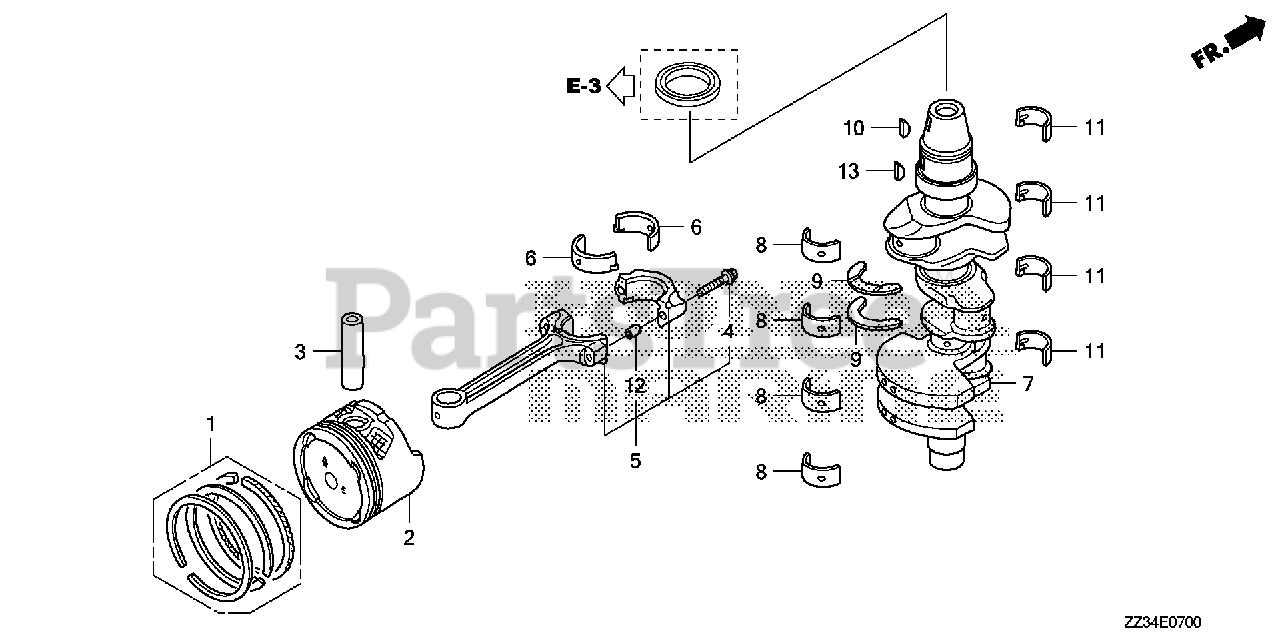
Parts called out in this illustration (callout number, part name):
1	RING SET, PISTON (STD) (RIKEN)
2	PISTON
3	PIN, PISTON
4	BOLT, CONNECTING ROD
5	ROD, CONNECTING
6	BEARING A, CONNECTING ROD (BLUE) (DAIDO)
6	BEARING B, CONNECTING ROD (BLACK) (DAIDO)
6	BEARING C, CONNECTING ROD (BROWN) (DAIDO)
6	BEARING D, CONNECTING ROD (GREEN) (DAIDO)
6	BEARING E, CONNECTING ROD (YELLOW) (DAIDO)
6	BEARING F, CONNECTING ROD (PINK) (DAIDO)
6	BEARING G, CONNECTING ROD (RED) (DAIDO)
7	CRANKSHAFT
8	BEARING B, MAIN (UPPER) (BLACK) (DAIDO)
8	BEARING C, MAIN (UPPER) (BROWN) (DAIDO)
8	BEARING D, MAIN (UPPER) (GREEN) (DAIDO)
8	BEARING E, MAIN (UPPER) (YELLOW) (DAIDO)
8	BEARING F, MAIN (UPPER) (PINK) (DAIDO)
8	BEARING G, MAIN (UPPER) (RED) (DAIDO)
8	BEARING H, MAIN (UPPER) (WHITE) (DAIDO)
9	WASHER, THRUST
10	KEY, SPECIAL WOODRUFF (25X18)
11	BEARING B, MAIN (LOWER) (BLACK) (DAIDO)
11	BEARING C, MAIN (LOWER) (BROWN) (DAIDO)
11	BEARING D, MAIN (LOWER) (GREEN) (DAIDO)
11	BEARING E, MAIN (LOWER) (YELLOW) (DAIDO)
11	BEARING F, MAIN (LOWER) (PINK) (DAIDO)
11	BEARING G, MAIN (LOWER) (RED) (DAIDO)
11	BEARING H, MAIN (LOWER) (WHITE) (DAIDO)
12	PIN, DOWEL (8X10)
13	KEY, WOODRUFF (25X14)
